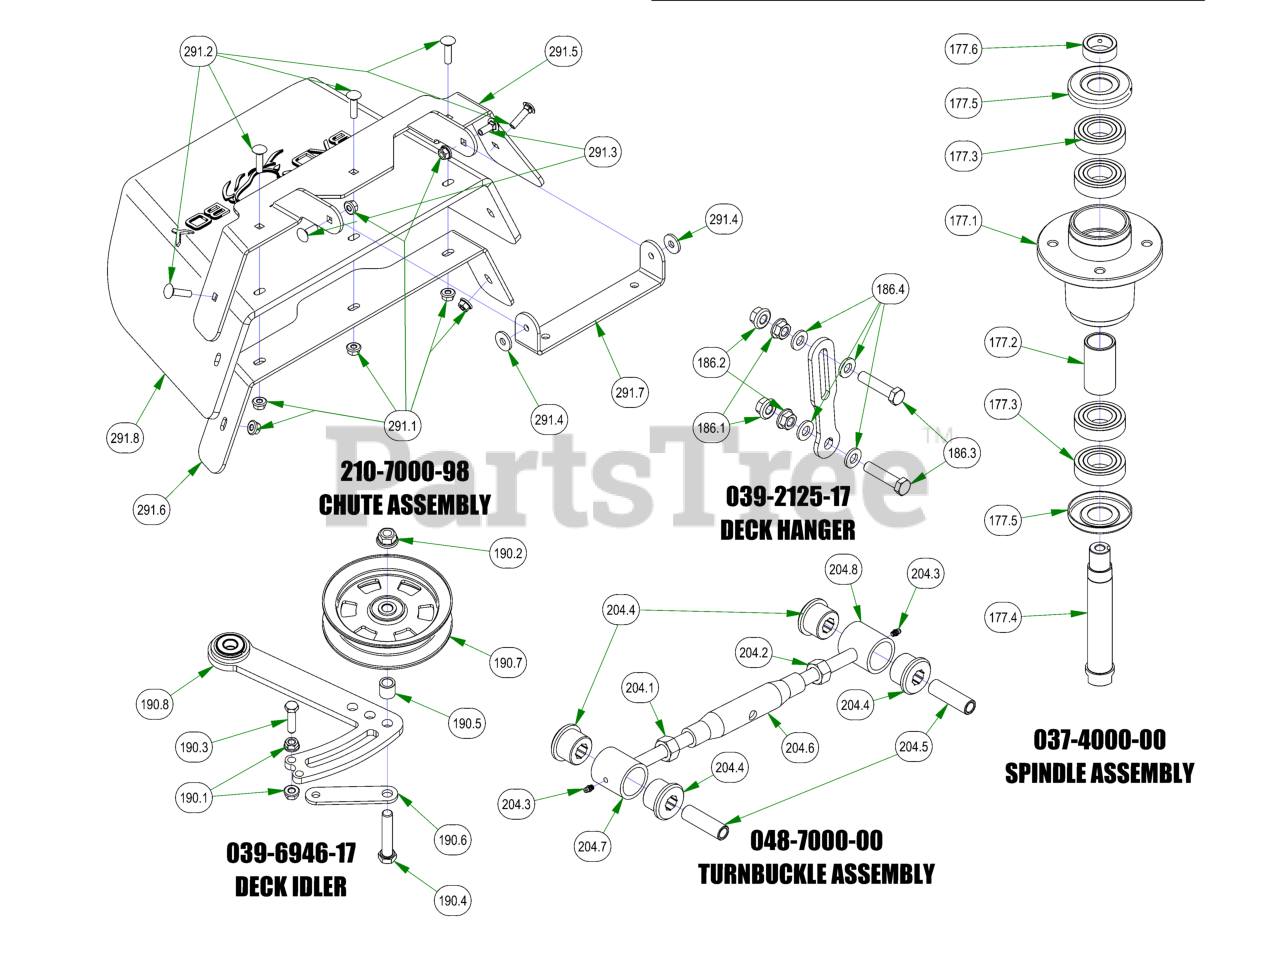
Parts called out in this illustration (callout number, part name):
177	OUTLAW SPINDLE ASSEMBLY
177.1	4000 Series Spindle Housing
177.2	4000 Series Spindle Spacer
177.3	Bearing - 6206
177.4	Spindle Shaft
177.5	Spindle Dust Cap
177.6	Locking Collar w/ 1/4"-20 Set Screw
186	Deck Hanger Assembly
186.1	1/2-13 HEX SERRATED FLANGE NUT HARD/ZINC
186.2	1/2-13 NYLON INSERT FLANGE LOCKNUT ZINC
186.3	1/2-13 X 2-1/4 HEX CAP SCREW (GR.5) ZINC
186.4	.505 ID X 1.000 OD X .125 THICK FLAT WASHER NYLON
186.5	Deck Hangar
190	2019 Renegade Deck Idler
190.1	3/8-16 HEX SERRATED FLANGE NUT HARD/ZINC
190.2	1/2-13 NYLON INSERT FLANGE LOCKNUT ZINC
190.3	3/8-16 X 1-1/2 HEX CAP SCREW (GR.5) ZINC
190.4	1/2-13 X 2-3/4 HEX CAP SCREW (GR.5) ZINC
190.5	.51 ID X .75 OD X .75 LGTH SOLID SPACER ZINC
190.6	Belt Tensioner Retainer Plate
190.7	5" Idler Pully
190.8	2019 Deck Tensioner
204	Turnbuckle
204.1	11/16-12 Hex Nut-2015 Toplink
204.2	11/16-12 Lefthand Hex Nut-Topl
204.3	1/4" Press in Grease Fitting
204.4	Polyeurethane Bushing
204.6	2015 Outlaw Toplink Body
204.7	2015 Outlaw Toplink RH End
204.8	2015 Outlaw Toplink LH End
291	2019 Outlaw Gen2 Chute Assembly
291.1	5/16-18 NYLON INSERT FLANGE LOCKNUT ZINC
291.2	5/16-18 X 1-1/4 CARRIAGE BOLT ZINC
291.3	5/16-18 X 7/8 CARRIAGE BOLT ZINC
291.4	.360 ID X .983 OD X .120 THICK FLAT WASHER NYLON
291.5	2019 Upper Chute Bracket
291.6	2019 Lower Chute Bracket
291.7	2019 Chute Hanger
291.8	2019 Belted Chute with Logo
